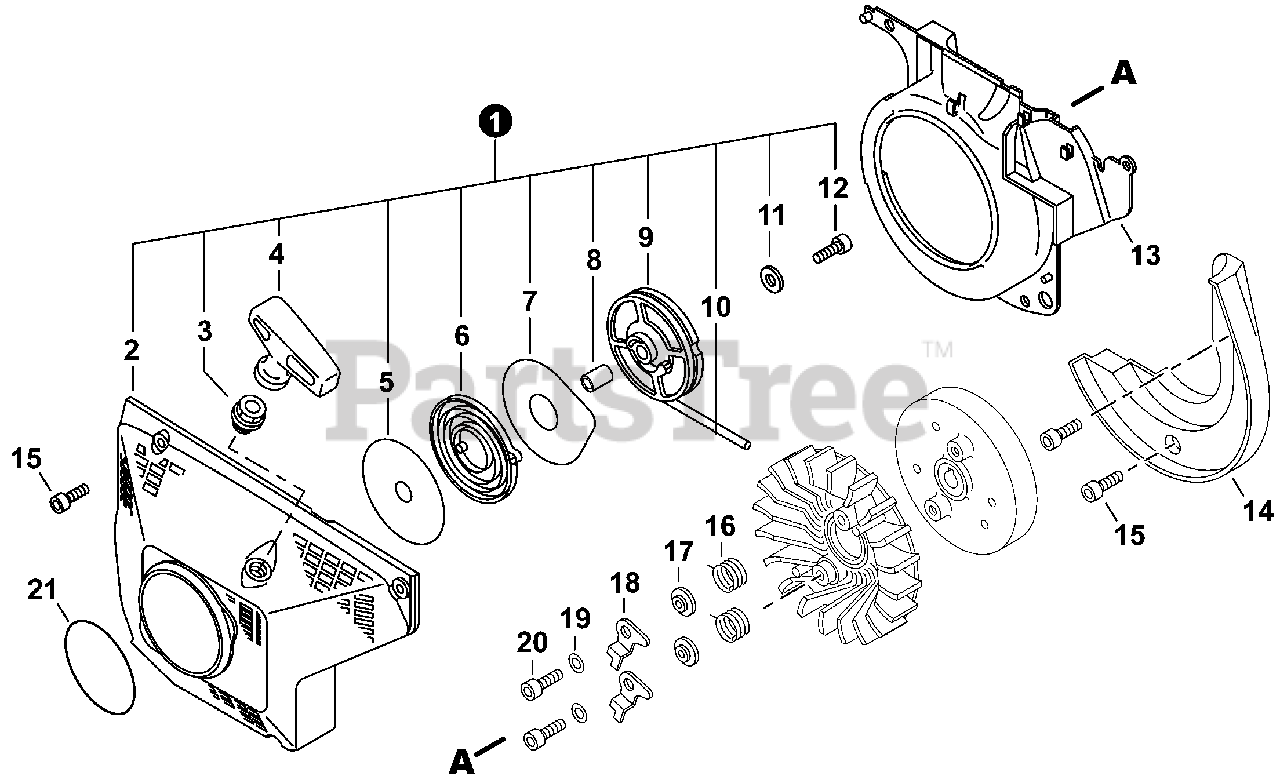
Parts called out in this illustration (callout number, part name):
1	STARTER ASSY - GRAY
1	STARTER ASSY - ORANGE
2	CASE, STARTER - ORANGE
3	GUIDE, ROPE
4	GRIP, STARTER
5	PLATE, STARTER
6	SPRING, RECOIL
7	PLATE, STARTER
9	REEL, ROPE
10	ROPE, STARTER 4.0x950
11	WASHER 5.2x16x1.0
12	BOLT 5x14
13	COVER, FAN - GRAY
13	COVER, FAN - ORANGE
14	PLATE, GUIDE - ORANGE
15	BOLT 5x20
16	SPRING, RETURN
17	SPACER, PAWL
18	PAWL, STARTER
19	WASHER 5.5x12x0.8
20	BOLT 5x30
21	LABEL - ECHO
